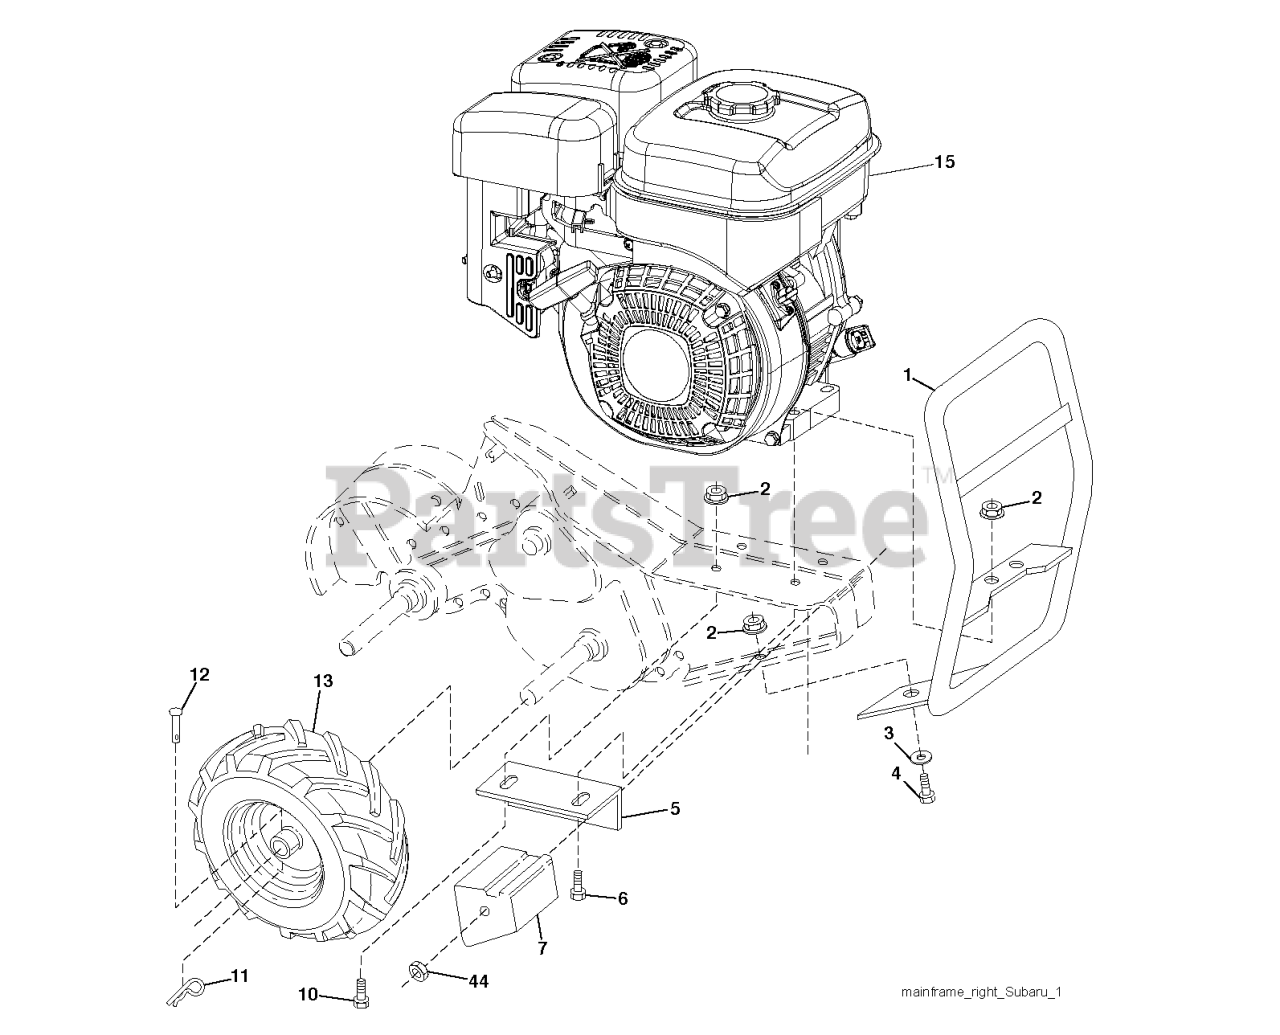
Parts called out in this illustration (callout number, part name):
1	RP.BUMPER.ASM.TILLER.
2	LOCKNUT-FLANGE 5/16-18
3	WASHER
4	BOLT
5	DNO BRACKET RH CRT
6	BOLT, HEX 5/16-18X1-3/4
7	COUNTERWEIGHT, RH
10	BOLT
11	RETAINER M
12	RIVET,DRILLED
13	VALVE STEM LT
13	RIM.ASM.6".SILVER
13	TIRE.13X5-6.CHEVRON.TILLER
